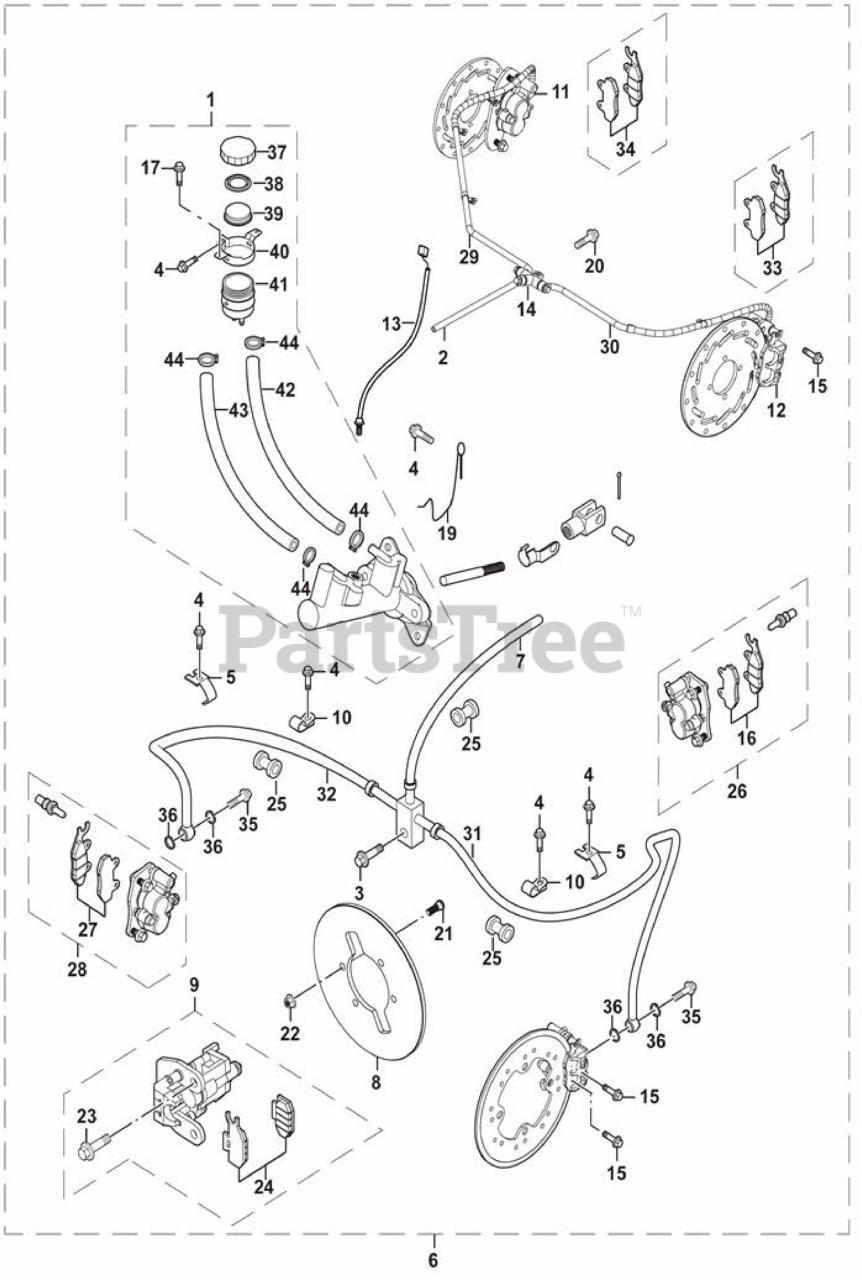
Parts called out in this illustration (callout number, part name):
2	Middle brake oil pipe
3	Hexagon Flange Bolt M6X25
4	Cross Large Plate Head Screw M6X12
5	Fixed Clip III,Hydraulic Oil Pipe
6	Disk Brake Assy
7	Front Hydraulic Oil Pipe
8	Parking brake rotor
9	Middle Brake Assy
10	Oil Pipe Clip I
11	Rear Right Brake Caliper
12	Rear Left Brake Caliper
13	Rear braking lights switch
15	Hexagon Flange bolt M10X1.25X22
16	Front Left Brake Pad Assy
17	Hexagon Flange Bolt M6X16
18	Hexagon Flange Bolt M6X20
19	Fixing Spring, Oil Pipe
20	Hexagon Flange BoltM6X30
21	Inner Hexagon Bolt M8X20
22	Hexagon Flange Self-Lock Nuts (With Metallic Insert) M6
23	Hexagon Flange BoltM10X1.25X55
24	Outer Brake Pad
24	Inner Brake Pad
25	Oil pipe rubber hold
26	Front Left Brake Caliper
27	Front Right Brake Pad Assy
28	Front Right Brake Caliper
29	Rear brake oil pipe(R)
30	Rear brake oil pipe(L)
31	Front oil pipe
32	Front oil pipe
33	Rear Left Brake Caliper
34	Rear Right Brake Caliper
35	hydraulic oil pipe Bolt I
36	hydraulic oil pipe washer
37	Braking Cup cover
38	Braking Cup Paper washer I
39	Braking Cup Paper washer II
40	Braking Cup Bracket
41	Braking Cup
42	Supplement Oil pipe I
43	Supplement Oil pipe II
44	Lock Clamp A
